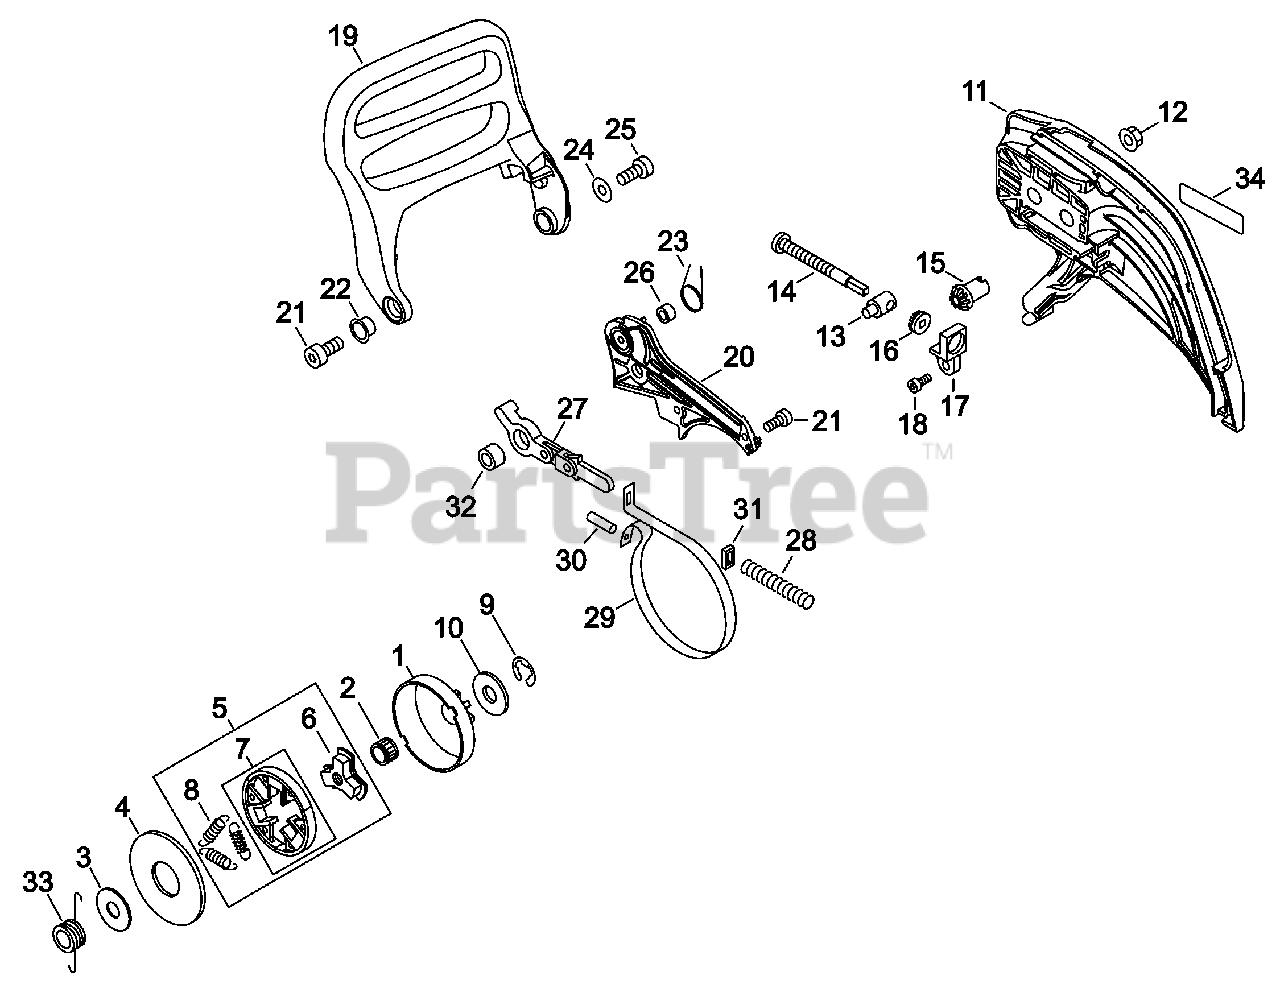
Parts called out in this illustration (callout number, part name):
1	DRUM, CLUTCH
2	BEARING, NEEDLE 8
3	PLATE, CLUTCH - SMALL
4	PLATE, CLUTCH - LARGE
5	CLUTCH ASSY
6	HUB, CLUTCH
7	SHOE SET, CLUTCH (3PCS)
8	SPRING, CLUTCH
10	WASHER 8.2×31×0.8
11	GUARD, SPROCKET
12	NUT, FLANGE M8×1.25
13	TENSIONER, CHAIN
14	SCREW, CHAIN TENSION
15	GEAR, BEVEL
16	GEAR, BEVEL
17	COLLAR 8
18	BOLT, TORX 4×12
19	LEVER, BRAKE
20	COVER, BRAKE
21	BOLT, TORX 4×12
22	COLLAR 10
23	SPRING, TORSION
24	WASHER 4.2×16.5×1
25	BOLT, TORX 4×20
26	SPACER 8×12×9
27	CONNECTOR, BRAKE
28	SPRING, COMPRESSION
29	BAND, BRAKE
30	PIN, SPRING 3x-9.8
32	SPACER 8×12×9
33	GEAR, WORM
34	LABEL, ECHO
